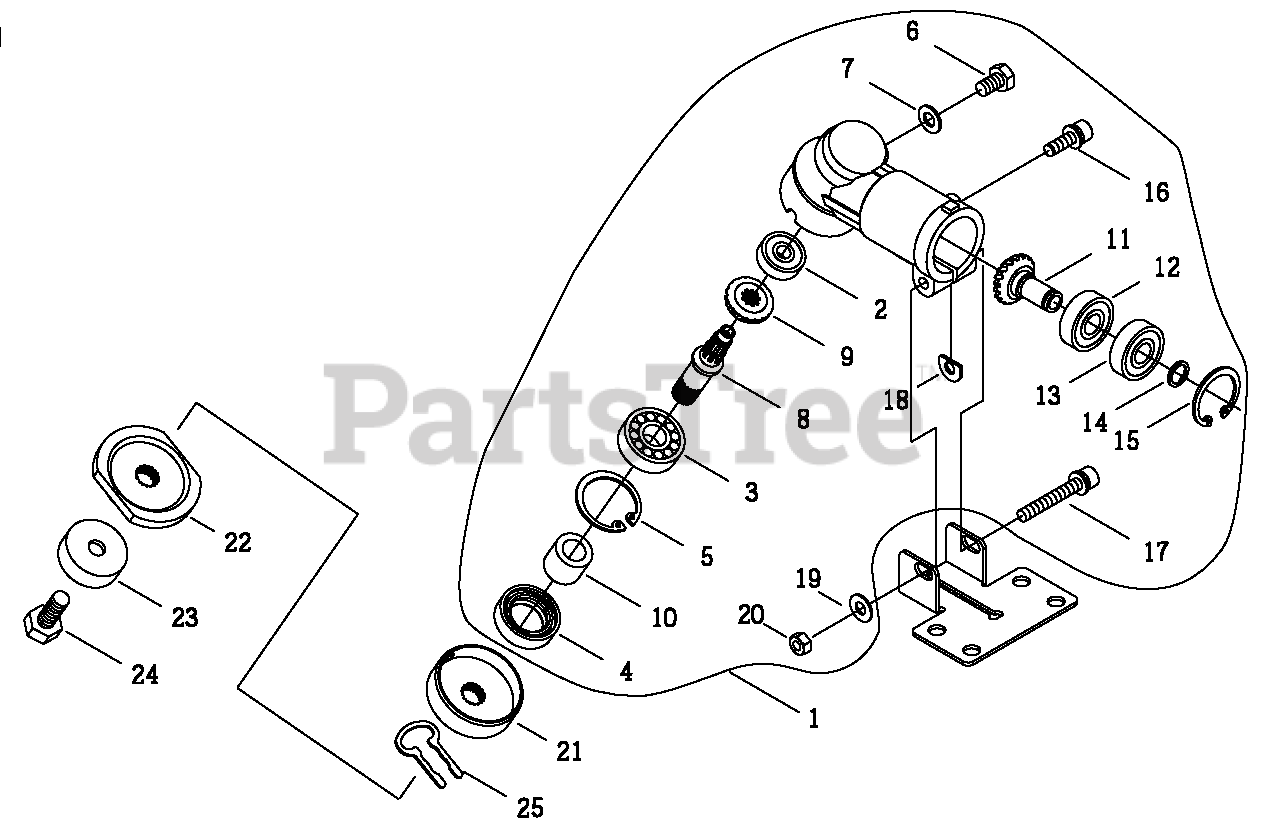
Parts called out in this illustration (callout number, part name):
1	GEAR CASE ASSY
2	BEARING, BALL - 626
3	BEARING, BALL - 6000
4	SEAL, OIL
5	RING, RETAINING - 26
6	BOLT - 6X10
7	WASHER - 8
8	GEAR - SHAFT
9	GEAR - BEVEL
10	COLLAR
11	GEAR - SHAFT
12	BEARING, BALL
13	BEARING, BALL - 608ZZ
14	RING, RETAINING
15	RING, RETAINING - 22
16	SCREW - 5X16
17	SCREW - 5X35
18	SHIM
19	WASHER - 5
20	NUT - 5
21	ADAPTOR, BLADE - UPPER
22	ADAPTOR, BLADE - LOWER
23	GUARD
24	BOLT - 7X18 -- LEFT HAND
25	CLIP
